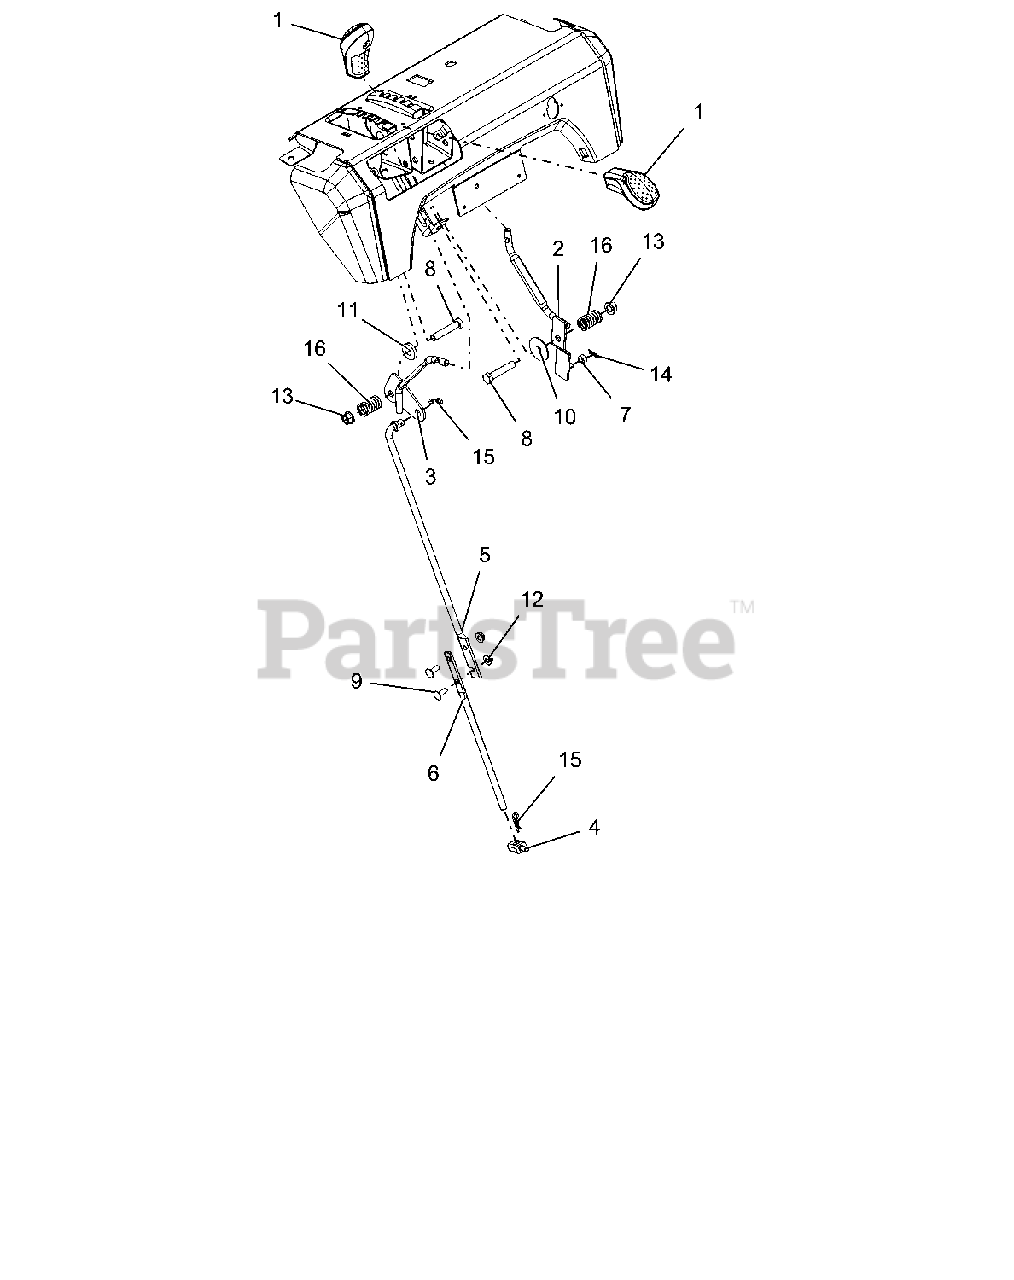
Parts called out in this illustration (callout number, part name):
1	KNOB, CONTROL, DASH
2	WELDMENT,LG DASH DEFL CONTROL
3	WELDMENT,LG DASH SPEED CONTROL
4	PIVOT,SHIFT ROD .375-16(TRUNN)
5	ROD, SHIFT - UPPER
6	ROD, SHIFT - LOWER
7	BSHG-SLV .265X.500X.219
8	@BLT-HEX .38-16X2.00 GR5 YWZC
9	@BLT-RDHDSQNK .25-20X.75 G5YZ
10	WSHR-FL-STL .380X1.50X.062 YWZ
11	WSHR-FL-STL .406X1.00X.188 YWZ
12	@NUT-LK-CTR-FLG .25-20 YWZC
13	@NUT-LK-TOP-FLG .38-16 YWZC
14	PIN-HAIR INT .06X.18X.77
15	PIN-HAIR INT .08X.18X1.18 YWZC
16	SG-COMP .125X.781X1.250
